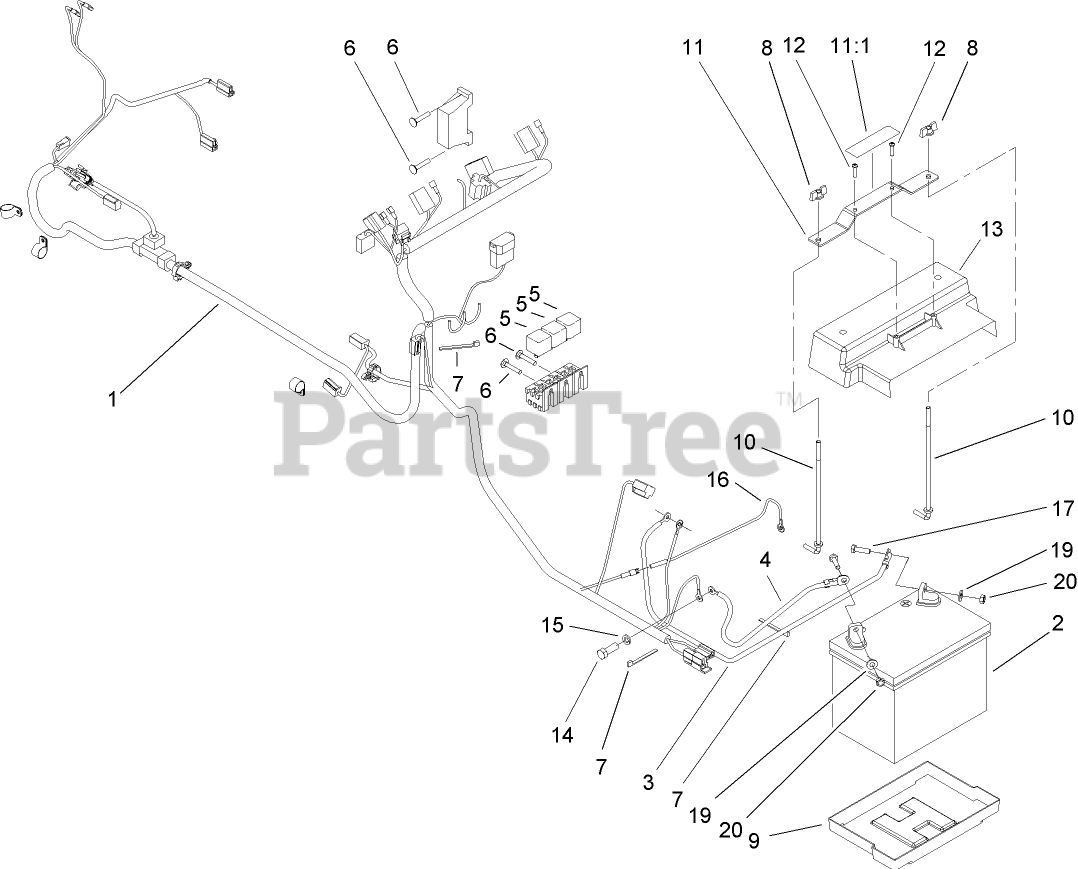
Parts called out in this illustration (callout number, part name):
1	HARNESS-WIRE
2	BATTERY-DRY
3	CABLE-BATTERY, RED 27IN
4	CABLE-BATTERY
5	RELAY
6	SCREW-HWH
7	TIE-CABLE
8	NUT-WING
9	TRAY-BATTERY
10	HOOK-RETAIN, BATTERY
11	STRAP ASM
11:1	DECAL-SURFACE, HOT
12	SCREW-PPH
13	SHIELD-BATTERY
14	SCREW-HHF
15	WASHER-LOCK
16	HARNESS-WIRE
17	SCREW-HH
19	WASHER-FLAT
20	NUT-LOCK, NI
